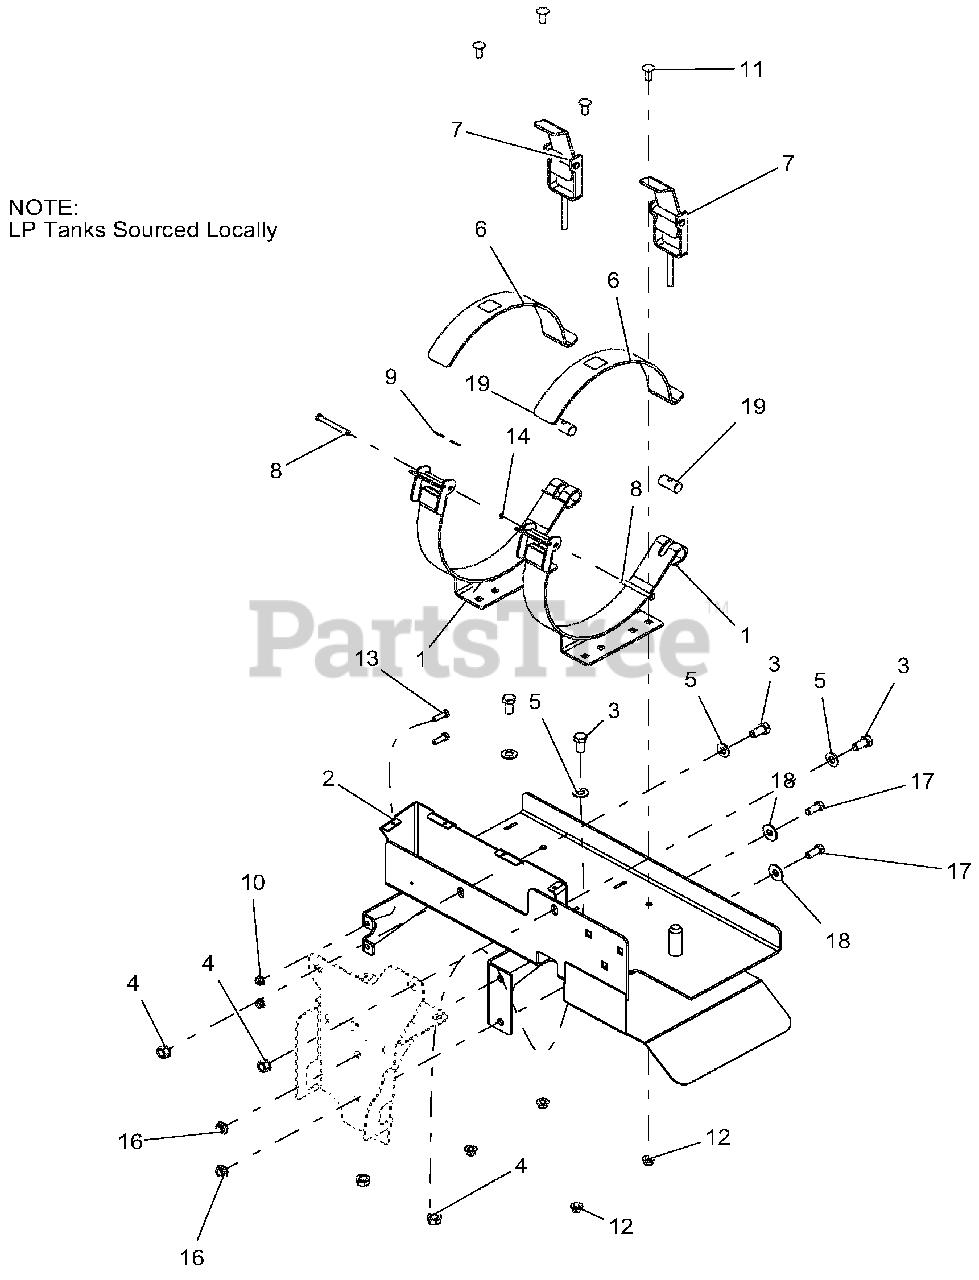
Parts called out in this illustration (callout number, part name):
1	WLDMT, CLAMP LP TANK
2	WLDMT, TANK -LH LP
3	BLT-HEX .50-13X1.00 GR5 YWZC
4	NUT, LK-TOP-FLG .50-13 YWZC
5	WSHR-FL-STL.531X1.06X.095YWZC
6	LP TANK CLAMP W/SAFETY DECAL
7	ASM, LP TANK HANDLE CLAMP
8	PIN, LP CLAMP
9	MAGNET, .75X.060, LP CLAMP
10	NUT, LK-TOP-FLG .312-18 YWZC
11	BLT-RDHDSQNK .38-16X1.00 G5 YWZC
12	NUT-LK-NYL-FLG .38-16 YWZC
13	BLT-HEX .31-18X1.00 GR5 YWZC
14	RG-RTNG-EXT .312X.025
16	NUT-LK-NYL-FLG .44-14 YWZC
17	BLT-HEX .44-14X1.00 GR5 YWZC
18	WSHR-FL-STL..50X1.25X.083 YWZ
19	PIVOT, LP CLAMP HANDLE
